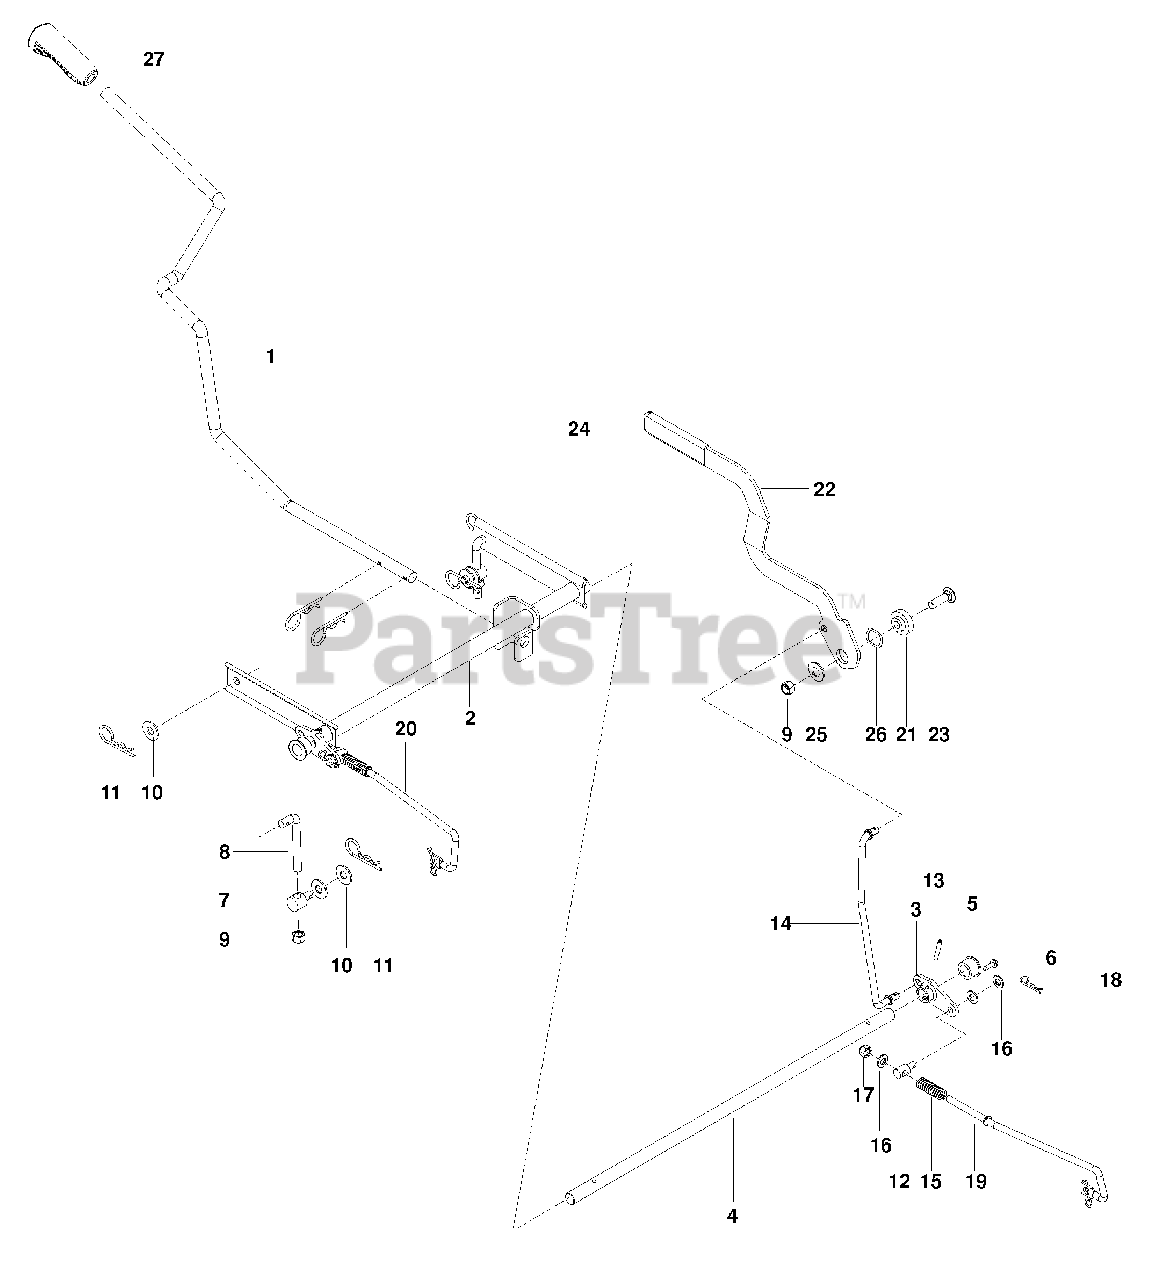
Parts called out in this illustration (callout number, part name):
1	HANDLE, LIFT
2	SHAFT, LIFT
3	BELLCRANK, BRAKE
4	ROD, BRAKE
5	BUSHING, PLASTIC
6	SCREW 10-24 x 5/8" WSH HD
8	L-ROD 31/8"
9	NUT 3/8-16 HEX NYLOC
10	WASHER 3/8 FLAT STD
12	SWIVEL, BRAKE
13	ROLL PIN 3/16"
14	LINKAGE, UPPER
16	WASHER 5/16 SAE FLAT
17	NUT 5/16-18 HEX NYLOC
18	HAIRPIN COTTER
19	LINKAGE, BRAKE RT
20	LINKAGE, BRAKE LT
21	PIVOT, BRAKE ARM
22	HANDLE, BRAKE
23	RHSNB 3/8-16 x 1 1/4
24	GRIP, BRAKE HANDLE
25	WASHER 7/16 SPRING DISK
26	WASHER, .825
27	GRIP, LIFT HANDLE
